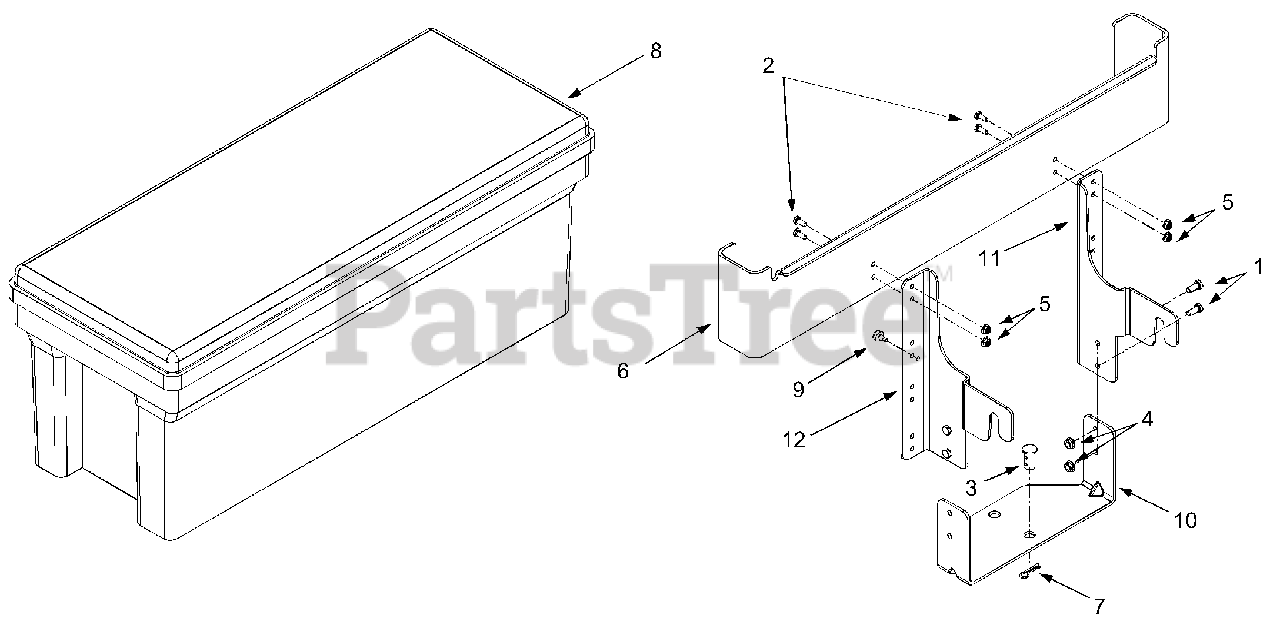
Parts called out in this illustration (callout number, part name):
1	Hex Cap Screw, 5/16-18 x .75
2	Hex Cap Screw, 1/4-20 x .62
3	Clevis Pin
4	Hex Flange Lock Nut, 5/16-18
5	Hex Flange Lock Nut, 1/4-20
8	Plastic Tool Box
9	Bumper, .62 Dia. x .3
